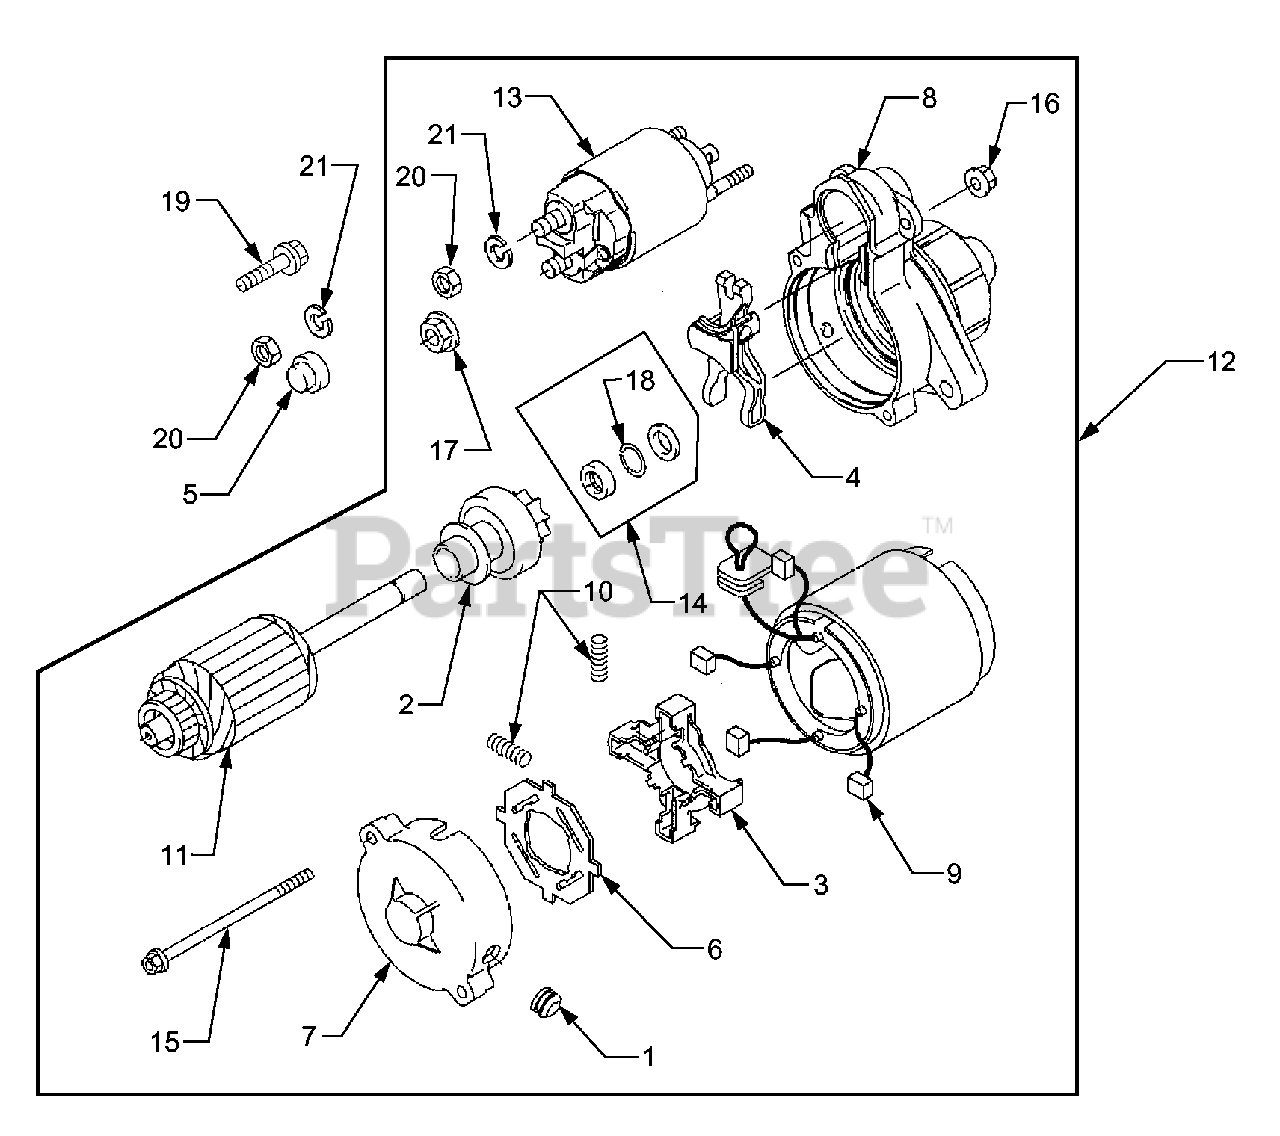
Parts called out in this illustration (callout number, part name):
2	Clutch Assembly
3	Holder, Brush
7	Cap, Starter End
8	Cone, Starter Nose
10	Spring, Brush
12	Starter, Electric
13	Solenoid, Starter
19	Bolt, Flanged
21	Washer, Spring
